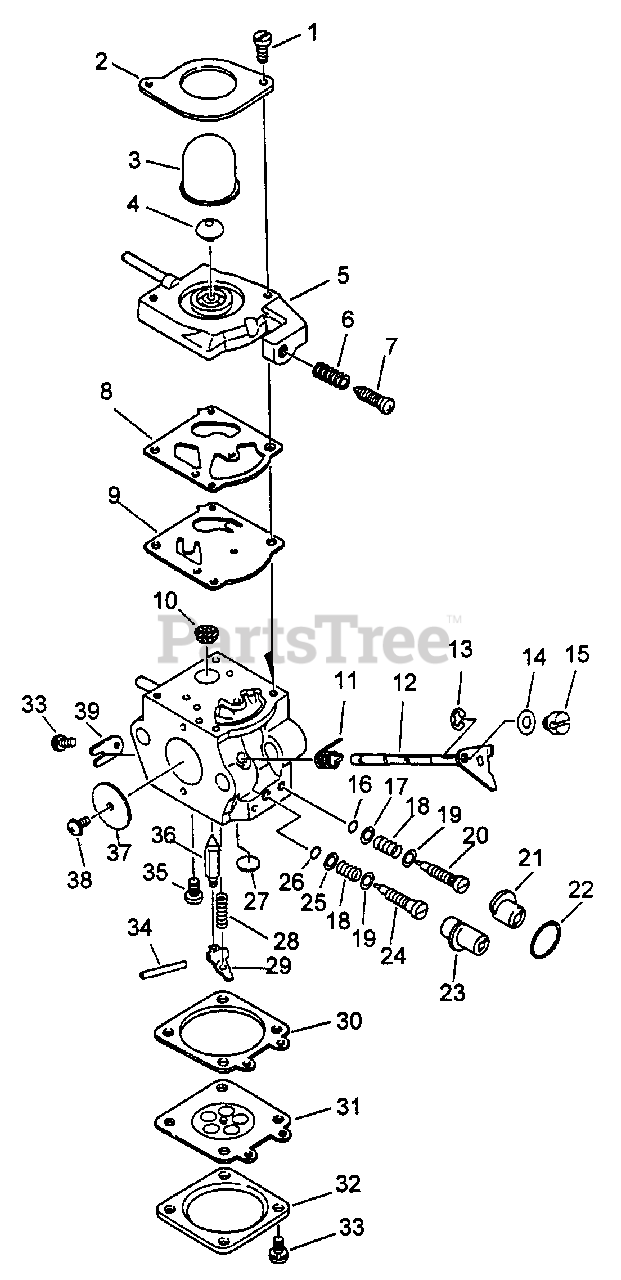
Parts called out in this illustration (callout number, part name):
2	RETAINER, PURGE BULB
3	BULB, PURGE
4	VALVE, CHECK
5	COVER, PUMP
6	SPRING, IDLE ADJUST
7	SCREW, IDLE ADJUST
8	GASKET, PURGE
9	DIAPHRAGM, PURGE
10	STRAINER
11	SPRING, THROTTLE RETURN
12	SHAFT, THROTTLE
13	RING, RETAINING
17	WASHER
18	SPRING
19	WASHER
20	NEEDLE - HIGH SPEED
21	CAP, LIMITER
23	CAP, LIMITER
24	NEEDLE - LOW SPEED
25	WASHER
26	O-RING
27	PLUG, WELCH
28	SPRING, METERING LEVER
29	LEVER, METERING
30	GASKET, METERING
31	DIAPHRAGM, METERING
32	COVER, METERING
33	SCREW
34	PIN, METERING LEVER
35	SCREW, METERING LEVER PIN
36	VALVE, INLET NEEDLE
37	VALVE, THROTTLE
39	CLIP, THROTTLE SHAFT
